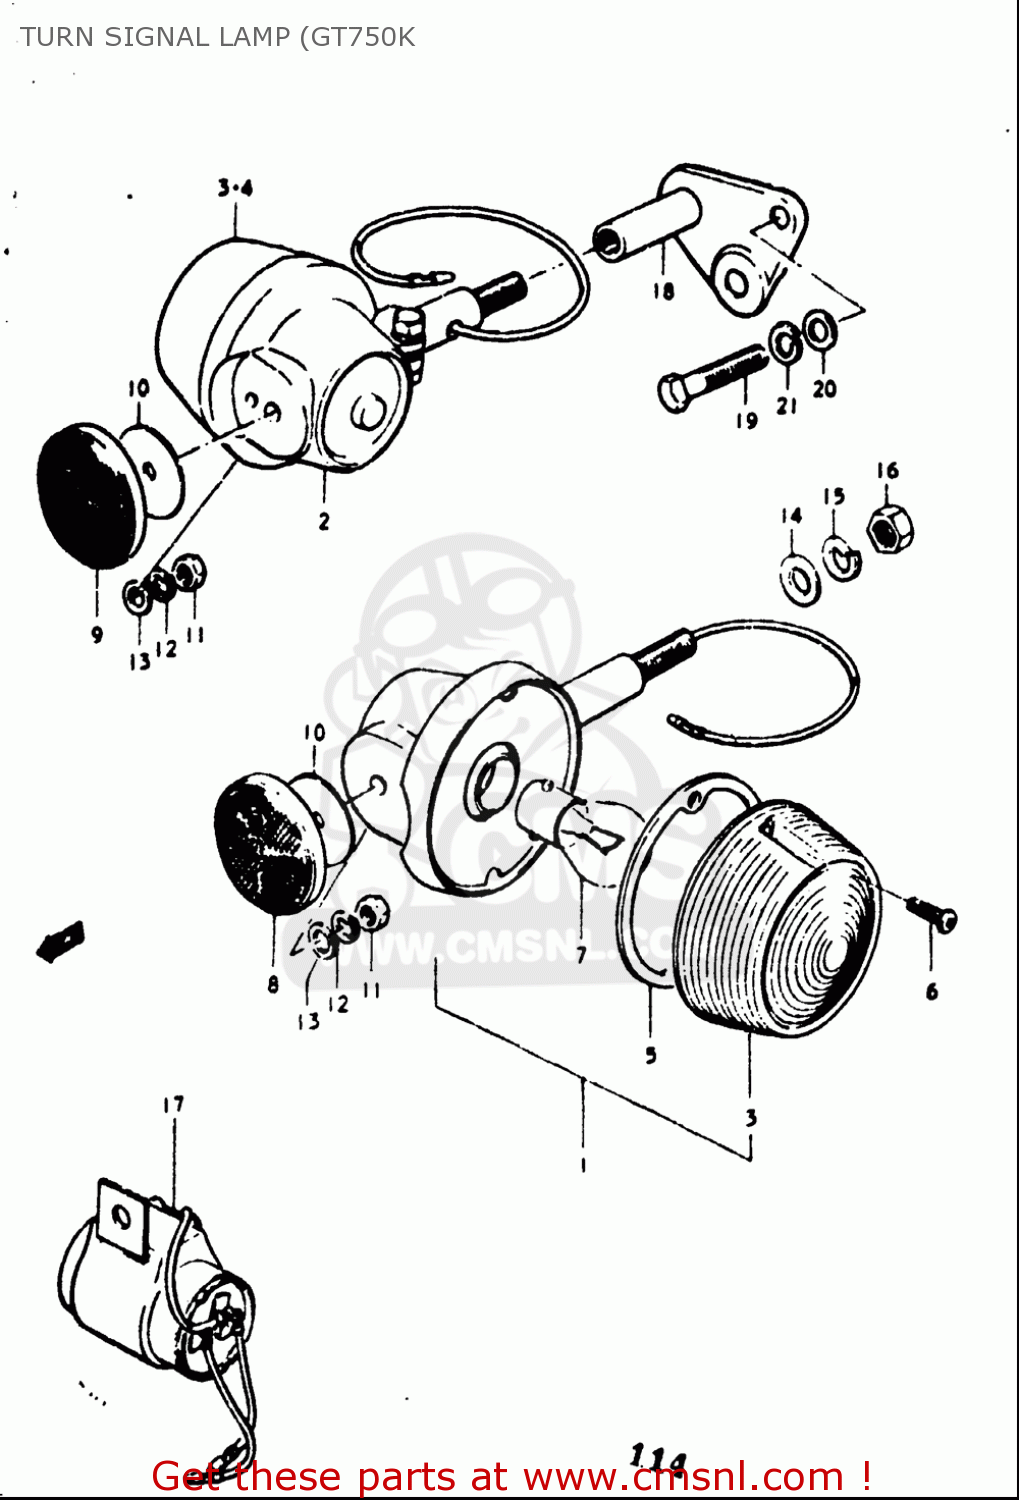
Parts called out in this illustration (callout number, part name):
3	LENS
5	GASKET,TURNSIGNAL LENS (NAS)
6	SCREW
7	BULB(12V23W,STANLEY,A4577A)
8	REFLEX REFLECTOR,RR
11	NUT
12	WASHER,LOCK
13	WASHER(5.5X18X1)
14	WASHER
15	WASHER,LOCK
16	NUT
17	RELAY,TURN SIGNAL
18	BRACKET, REAR TURN SIGNAL RH
19	BOLT
20	WASHER
21	WASHER,LOCK
